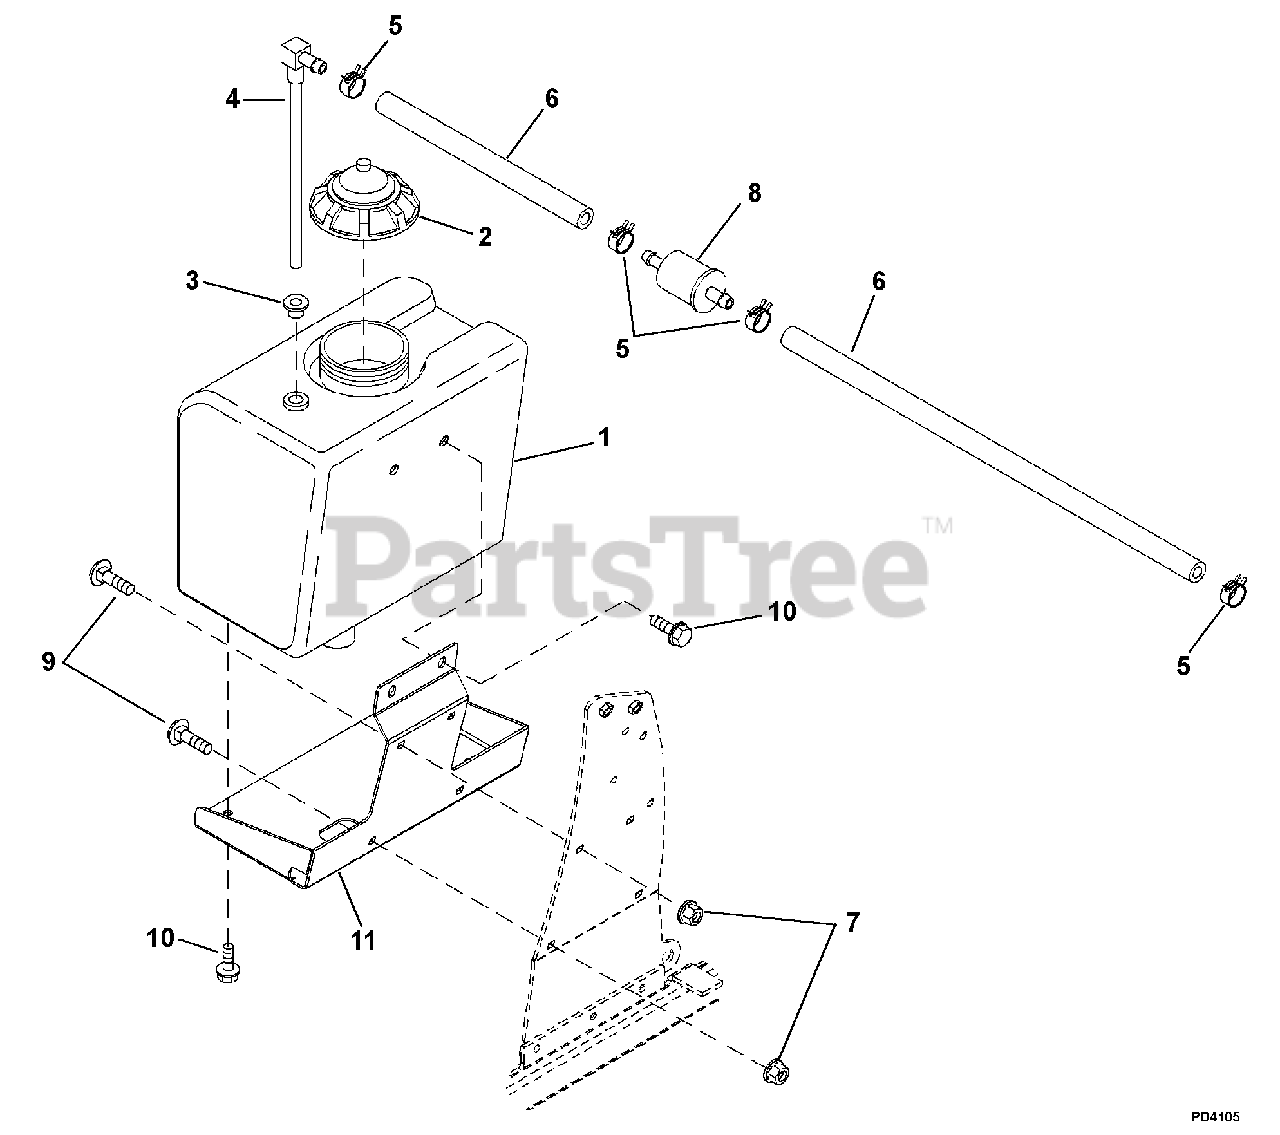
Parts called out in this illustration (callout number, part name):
1	Fuel Tank
2	Cap, Fuel
3	Grommet
4	Fuel Pickup
5	Clamp
6	Hose, 10 FT Service #
7	Nut, Locking, Nylon M10-1.5
8	Filter
9	Carriage Bolt, M10 x 1.5 x 25
10	Bolt, Hex M8 x 1.25 x 16
11	Bracket, Fuel Tank Mounting
